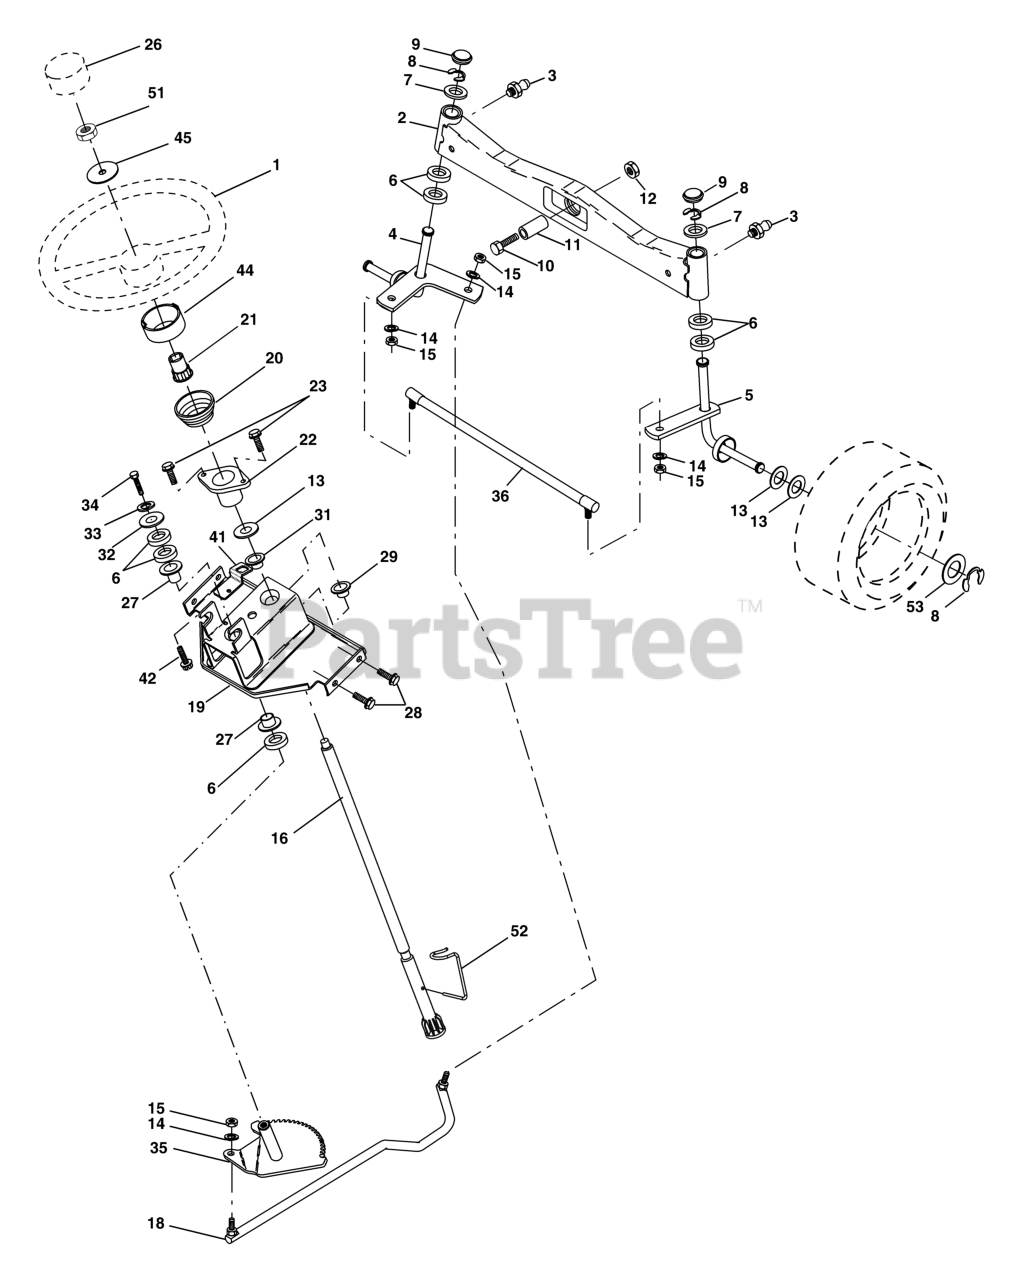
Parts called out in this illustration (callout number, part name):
1	STEERING WHEEL
2	AXLE.FRONT.CAST.MACHINE.W/ZERK
3	FITTING.GREASE.TAPERED
4	SPINDLE ASSY LH
5	SPINDLE ASM RH
6	THRUST WASHER
9	CAP.SPINDLE.BLACK
10	Bolt, Fin Hex 5/8-11 x 2-3/4
11	TUBE, PIVOT AXLE
12	NUT-LOC,FLANGE LT
14	WASHER, LOCK 3/8
15	NUT CROWNLOCK 3/8-24
16	SHAFT ASM, STEERING
18	DRAGLINK.VGT.54"
19	SUPPORT ASM., STEERING VGT
20	BOOT, STEERING
21	STEERING WHEEL ADAPTOR
22	BUSHING, STRG. BLK
23	SCREW.TT.#10-32X.5.3/8.FLANGE
26	CAP.WHEEL.STEERING.GREY
27	BRNG T
28	SCREW, 3/8-16X3/4
29	BEARING-FLANGE GT
31	BUSHING.NYLINER.
33	WASHER.LOCK.HVY.HLCL.SPR.5/16
34	BOLT.FIN.HEX.5/16-18X3/4
35	GEAR.ASM.SECTOR.PITMAN
36	ROD.TIE.NON-ADJUSTABLE
41	BRACKET INTERLOCK
42	Screw 5/16-18 x 1/2
44	EXTENSION STEERING PREMIUM
45	Washer 9/16 ID x 1-1/2 OD 11 Ga.
51	NUT.HEX.1/2-20
52	CLIP.STEERING
53	WASHER.HARDENED
